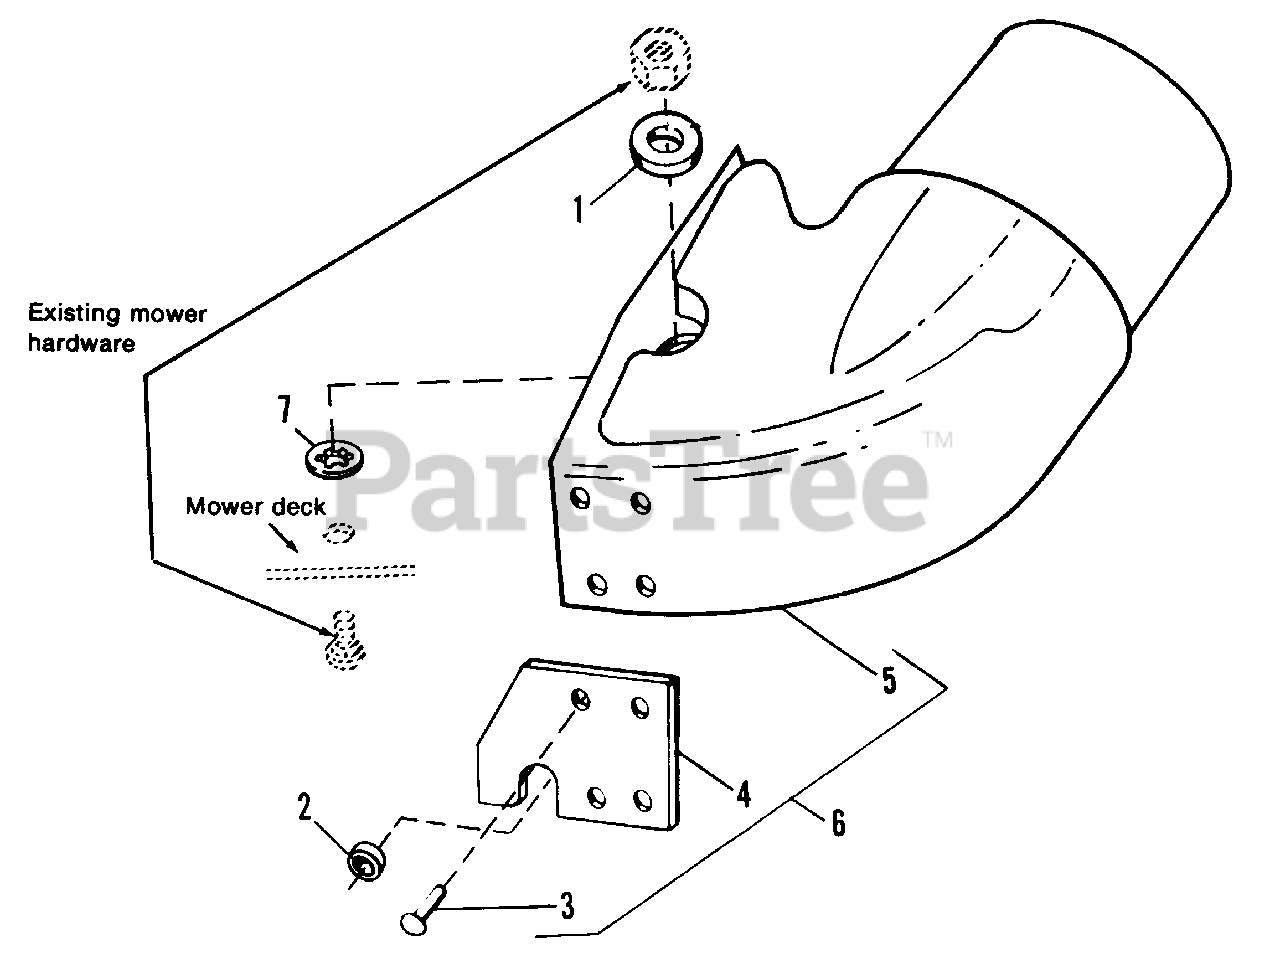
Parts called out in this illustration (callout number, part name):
1	WASHER
3	RIVET, Tubular, Oval Hd., 3/6 x 5/16
4	PLATE, Adaptor
6	ADAPTOR ASSY., 42" (Incl. Ref. Nos. 3, 4, 5)
7	NUT, Push Pal, 3/8
